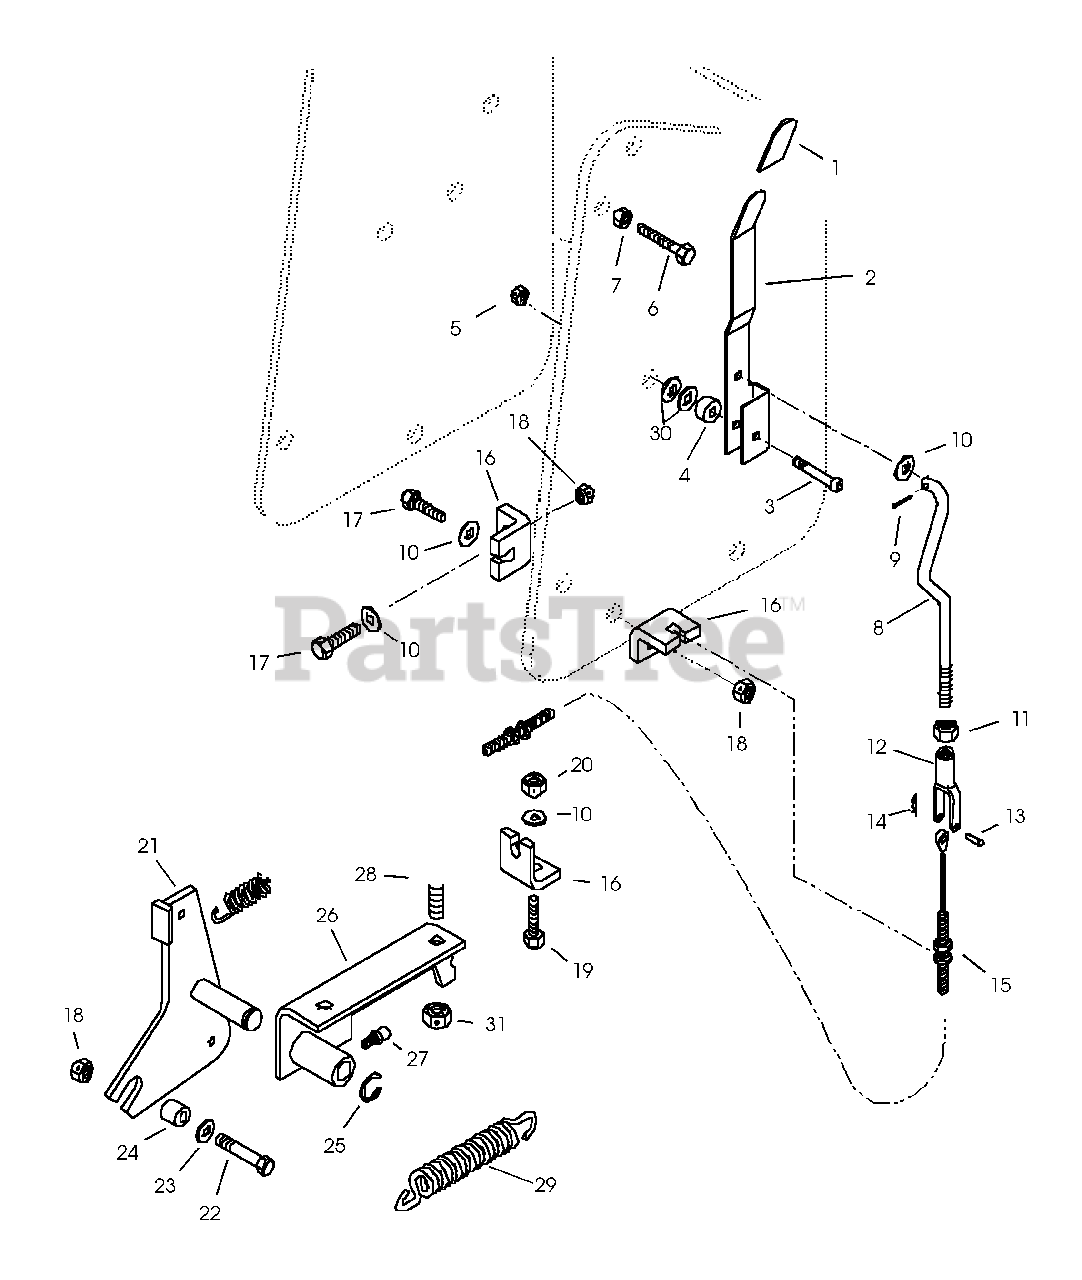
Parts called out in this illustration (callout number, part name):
1	Grip-Handle
2	Lever-Brake
3	Shoulder Bolt .38-16 X 1.25
5	Nut-Locking-Center .31-18
6	Bolt-Hex .25-20 x 1.5 Grade 5
7	Nut-Hex .25-20
8	Rod-Brake Link
9	Pin-Cotter .12 x .75
10	Washer-Flat-Steel .344 X .688 X 1.25
11	Nut-Jam .31-24
12	Yoke .312-24 X 2.25
13	Pin-Clevis .31 X .937
14	Pin-Hair Internal .08 x .18 x 1.18
15	Cable-Brake
16	Bracket-Cable
17	Bolt-Hex .25-20 x 1.00 Grade 5
18	Nut-Locking-Center .25-20
19	Bolt-Hex .31-18 x 1.00 Grade 5
20	Nut-Locking-Center .31-18
21	Weldment-Brake Arm
22	Bolt-Hex .25-20 x 1.75 Grade 5
23	Washer-Flat-Steel .281 x .620 x .065
24	Bushing-Sleeve .260 x .500 x .750
25	Ring-Retaining-External .392 x .042
26	Weldment-Brake Pivot
27	Fitting-Lube .25-28 x .256
28	Bolt-Hex .38-16 X 1.00 Grade 5
29	Spring-Tension .093 x .75 x 4.0
30	Washer-Flat-Steel .312 x .734 x .065
31	Nut-Locking-Center .38-16
